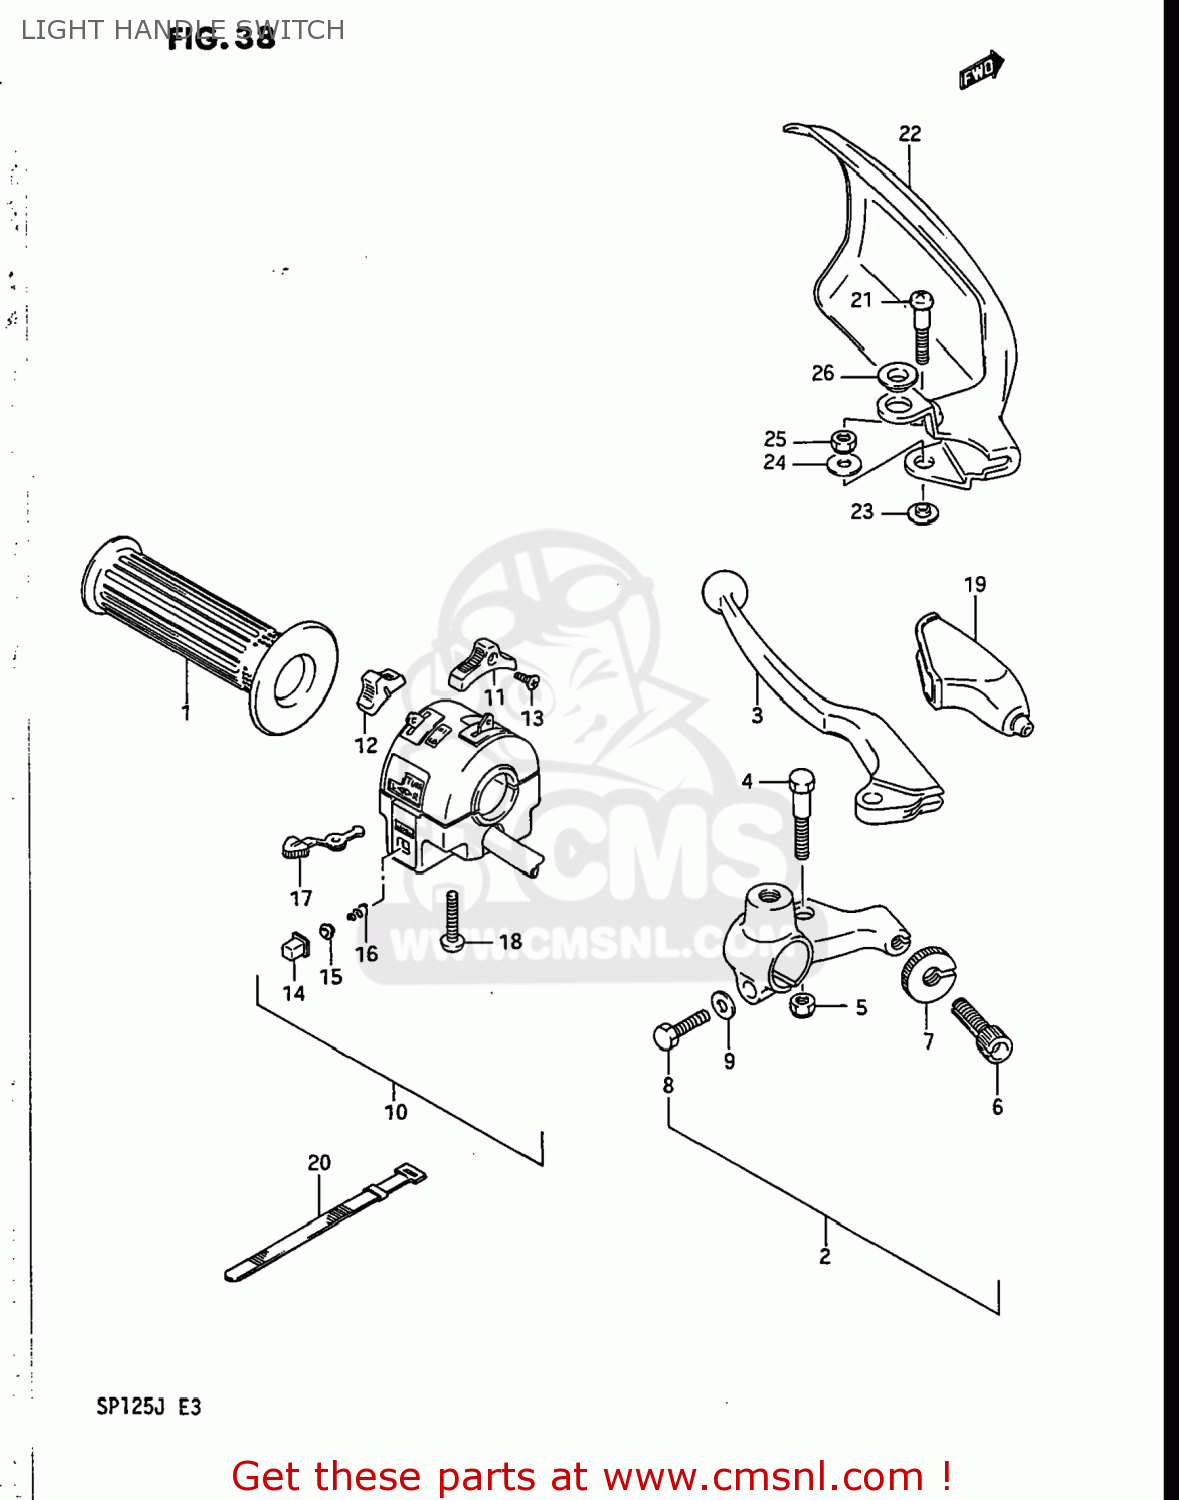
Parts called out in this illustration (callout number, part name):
1	GRIP,L
2	LEVER,CLUTCH
3	LEVER,CLUTCH
4	BOLT,LEVER PIVOT
5	NUT
6	ADJUSTER,CABLE
7	NUT,CABLE ADJUSTER LOCK
8	BOLT
9	WASHER
10	SWITCH ASSEMBLY,HANDLE,LEFT
11	KNOB,STOP
12	KNOB,DIMMER SWITCH
13	SCREW
14	BUTTON,HORN
15	CONTACT
16	SPRING
17	KNOB,TURNSIGNAL
18	SCREW
19	COVER,CLUTCH LEVER
20	CLAMP(L:120)
21	BOLT,LEVER PIVOT
22	COVER,KNUCKLE,LEFT
23	WASHER
24	WASHER(6.5X16X1.2)
25	NUT 6MM
26	WASHER
